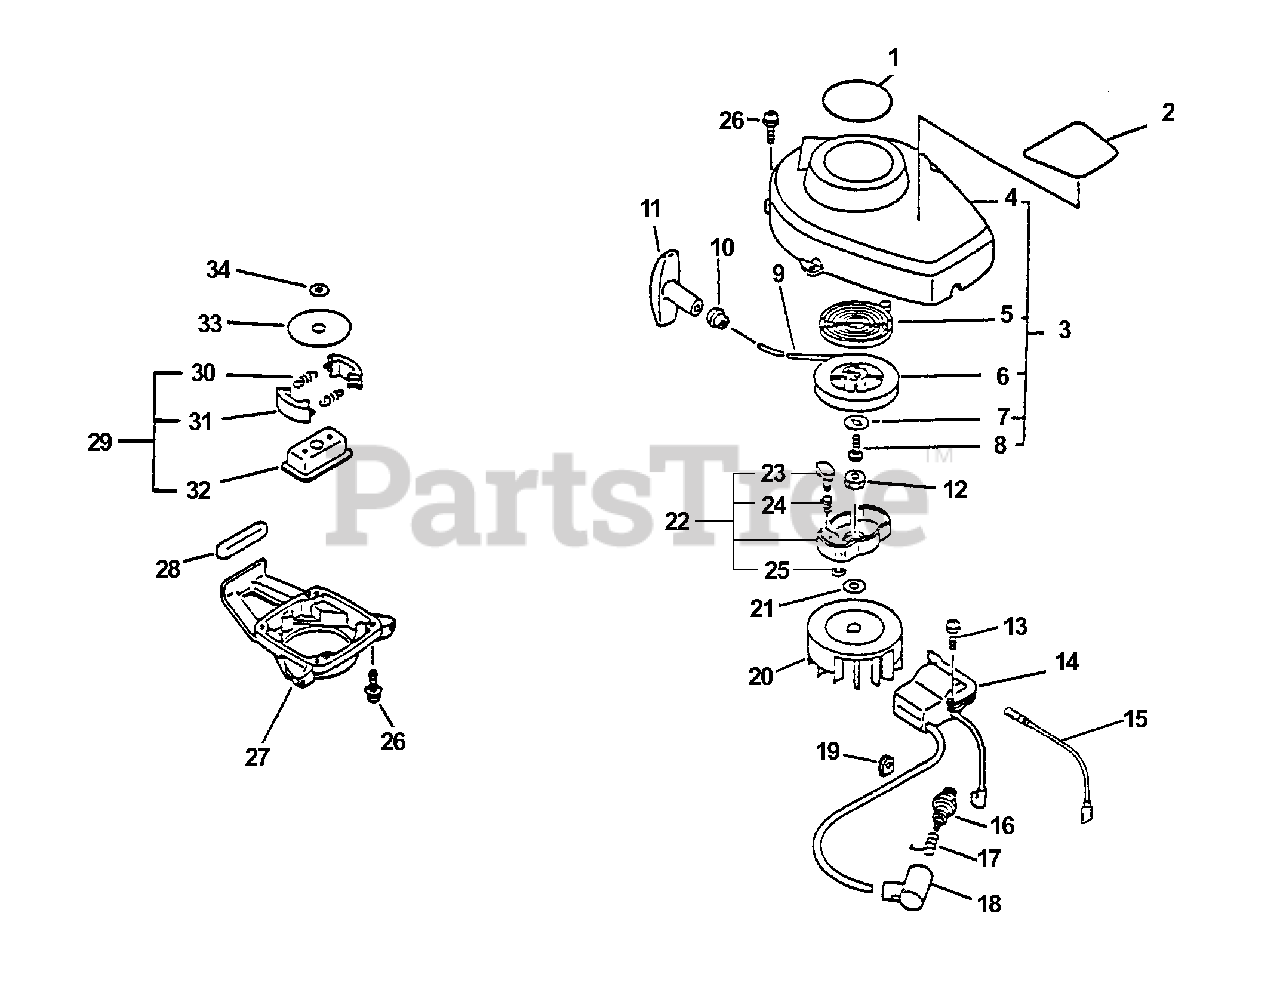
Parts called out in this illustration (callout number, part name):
1	LABEL, HC-2000
2	LABEL, CAUTION
3	STARTER ASSY
4	CASE, STARTER
5	SPRING, RECOIL
6	REEL, ROPE
7	WASHER
9	ROPE, STARTER
10	GUIDE, ROPE
11	GRIP, STARTER
13	SCREW 4×22
14	COIL, IGNITION
15	LEAD
16	SPARK PLUG - BPM-7Y
16	SPARK PLUG - RCJ7Y
17	TERMINAL, SPARK PLUG
18	CAP, SPARK PLUG
20	FLYWHEEL
21	WASHER 8.5×16×1.2
22	STARTER PAWL ASSY
23	PAWL, STARTER
24	SPRING, RETURN
25	E-RING 4
26	BOLT 4×16
27	HOUSING, CLUTCH
28	CUSHION, FUEL TANK
29	CLUTCH ASSY
30	SPRING, CLUTCH
31	SHOE, CLUTCH
32	HUB, CLUTCH
33	PLATE, CLUTCH
34	WASHER, CLUTCH
